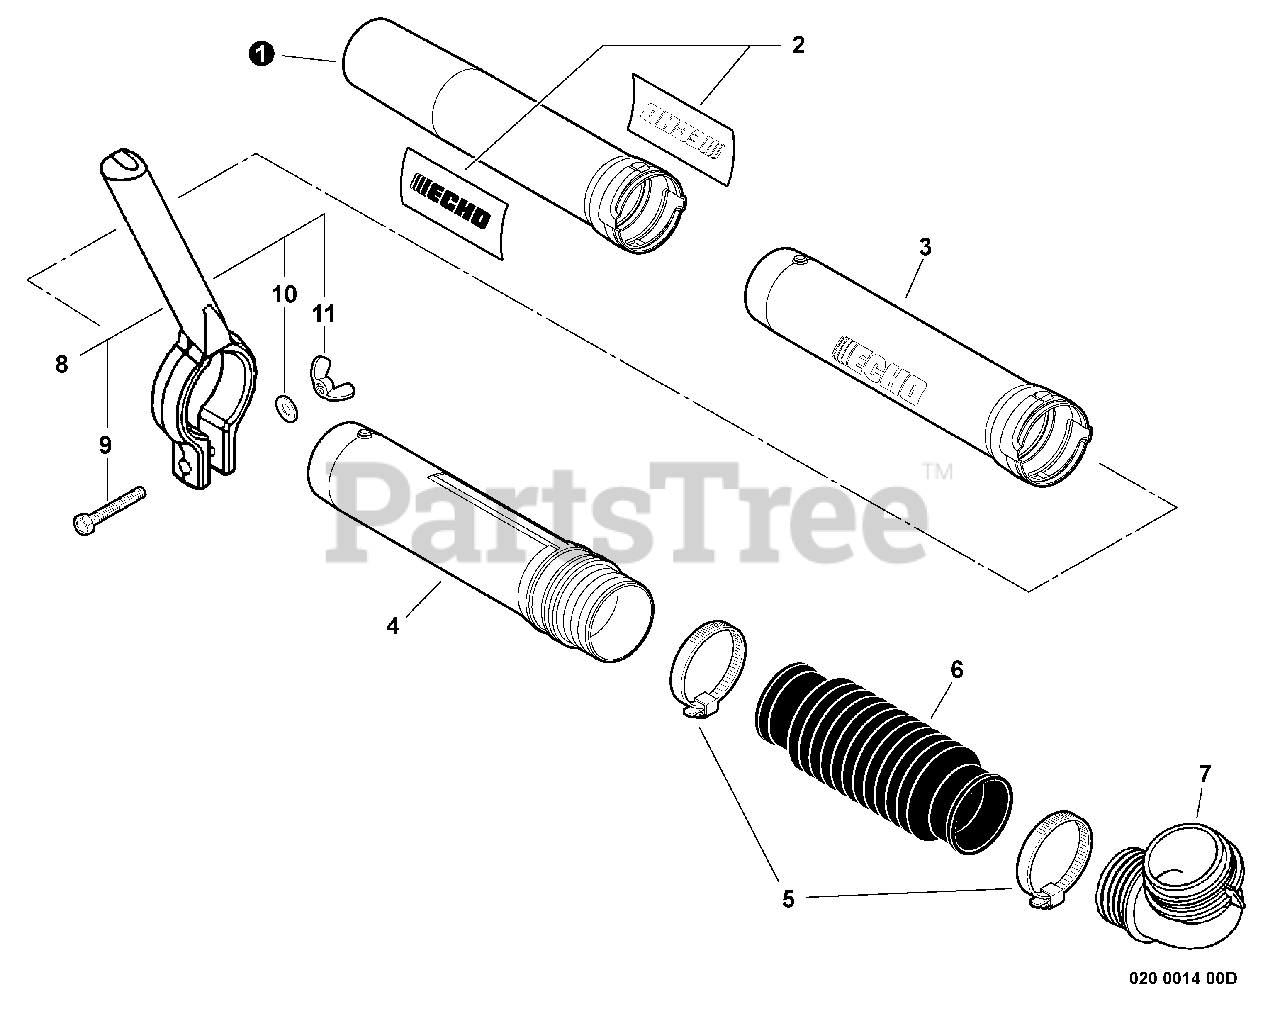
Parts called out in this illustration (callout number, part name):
1	TUBE, BLOWER - STRAIGHT
2	LABEL, ECHO BLOWER TUBE
3	TUBE, BLOWER - STRAIGHT
4	TUBE, BLOWER - SWIVEL
5	CLAMP 58.7 MM / 82.5 MM
6	TUBE, FLEXIBLE
7	TUBE, BLOWER - ELBOW
8	HANDLE ASSY, PB LARGE
9	BOLT 6×45
10	WASHER 6.5×11.5×0.8
11	NUT, WING 6
